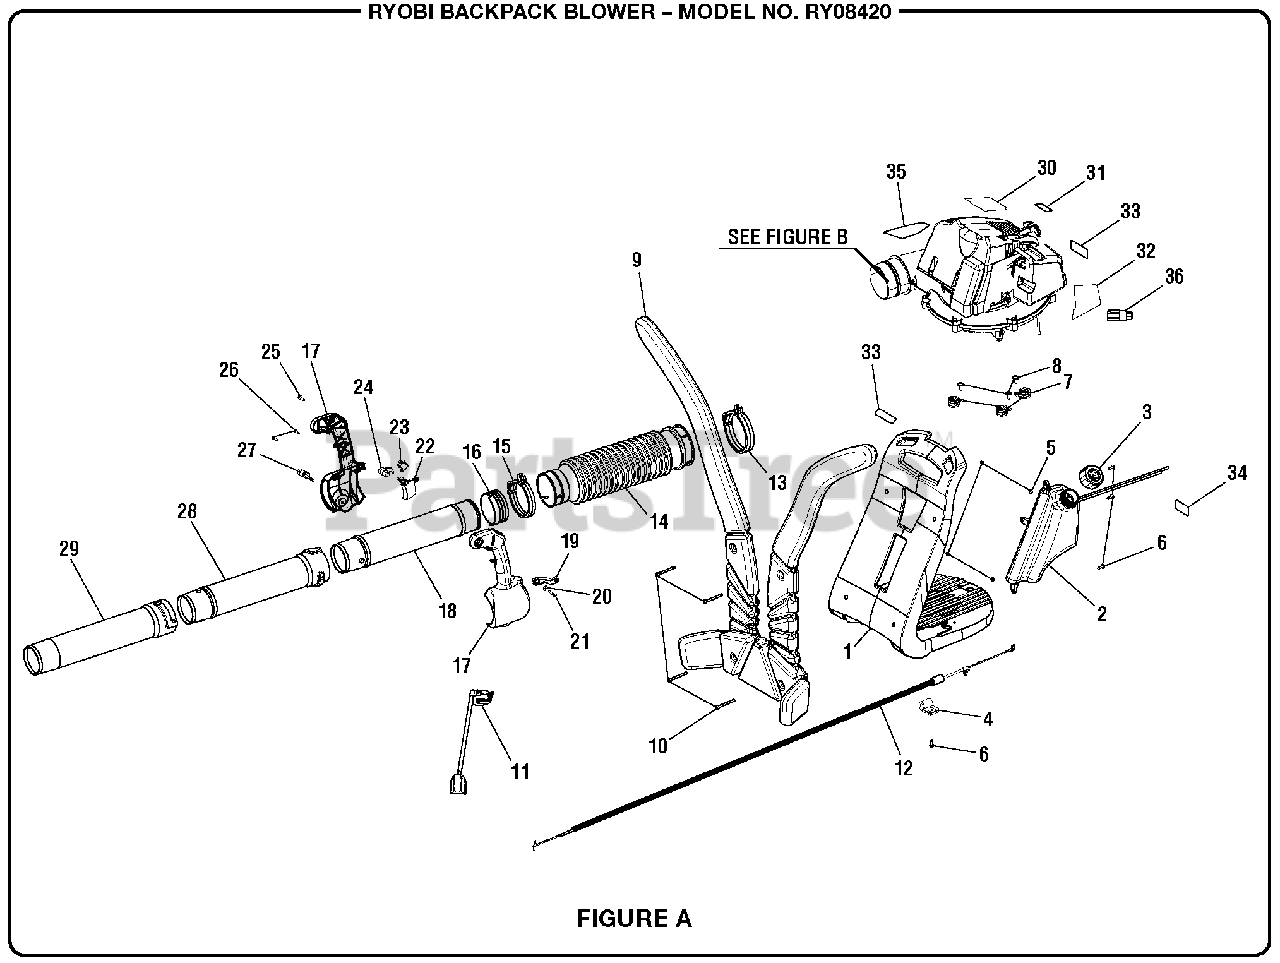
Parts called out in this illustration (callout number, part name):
2	Fuel Tank Assembly
3	Fuel Cap Assembly
4	Cable Clamp
5	Hex Nut (M5)
6	Screw (10-14 x 14 mm)
8	Screw (10-14 x 16 mm)
10	Shoulder Screw (M6, Special)
11	Ignition Module Assembly
12	Throttle Cable
13	Clamp Assembly (Large)
15	Clamp Assembly (Small)
16	Upper Blower Tube Bushing
17	Handle Assembly
18	Upper Tube
19	Cruise Lever
20	Washer (OD12 x ID4.3 x 1.5t)
21	Screw (8-14 x 25 mm)
23	Stop Switch
24	Trigger Lock
25	Screw (10-14 x 3/4 in.)
26	Screw (M4 x 16 mm, Pan Hd.)
28	Intermediate Tube
29	Tube Nozzle
30	Model Label
31	Choke Label
32	Start Instructions Label
33	Logo Label
34	Warning Label
35	Combustion Warning Label
